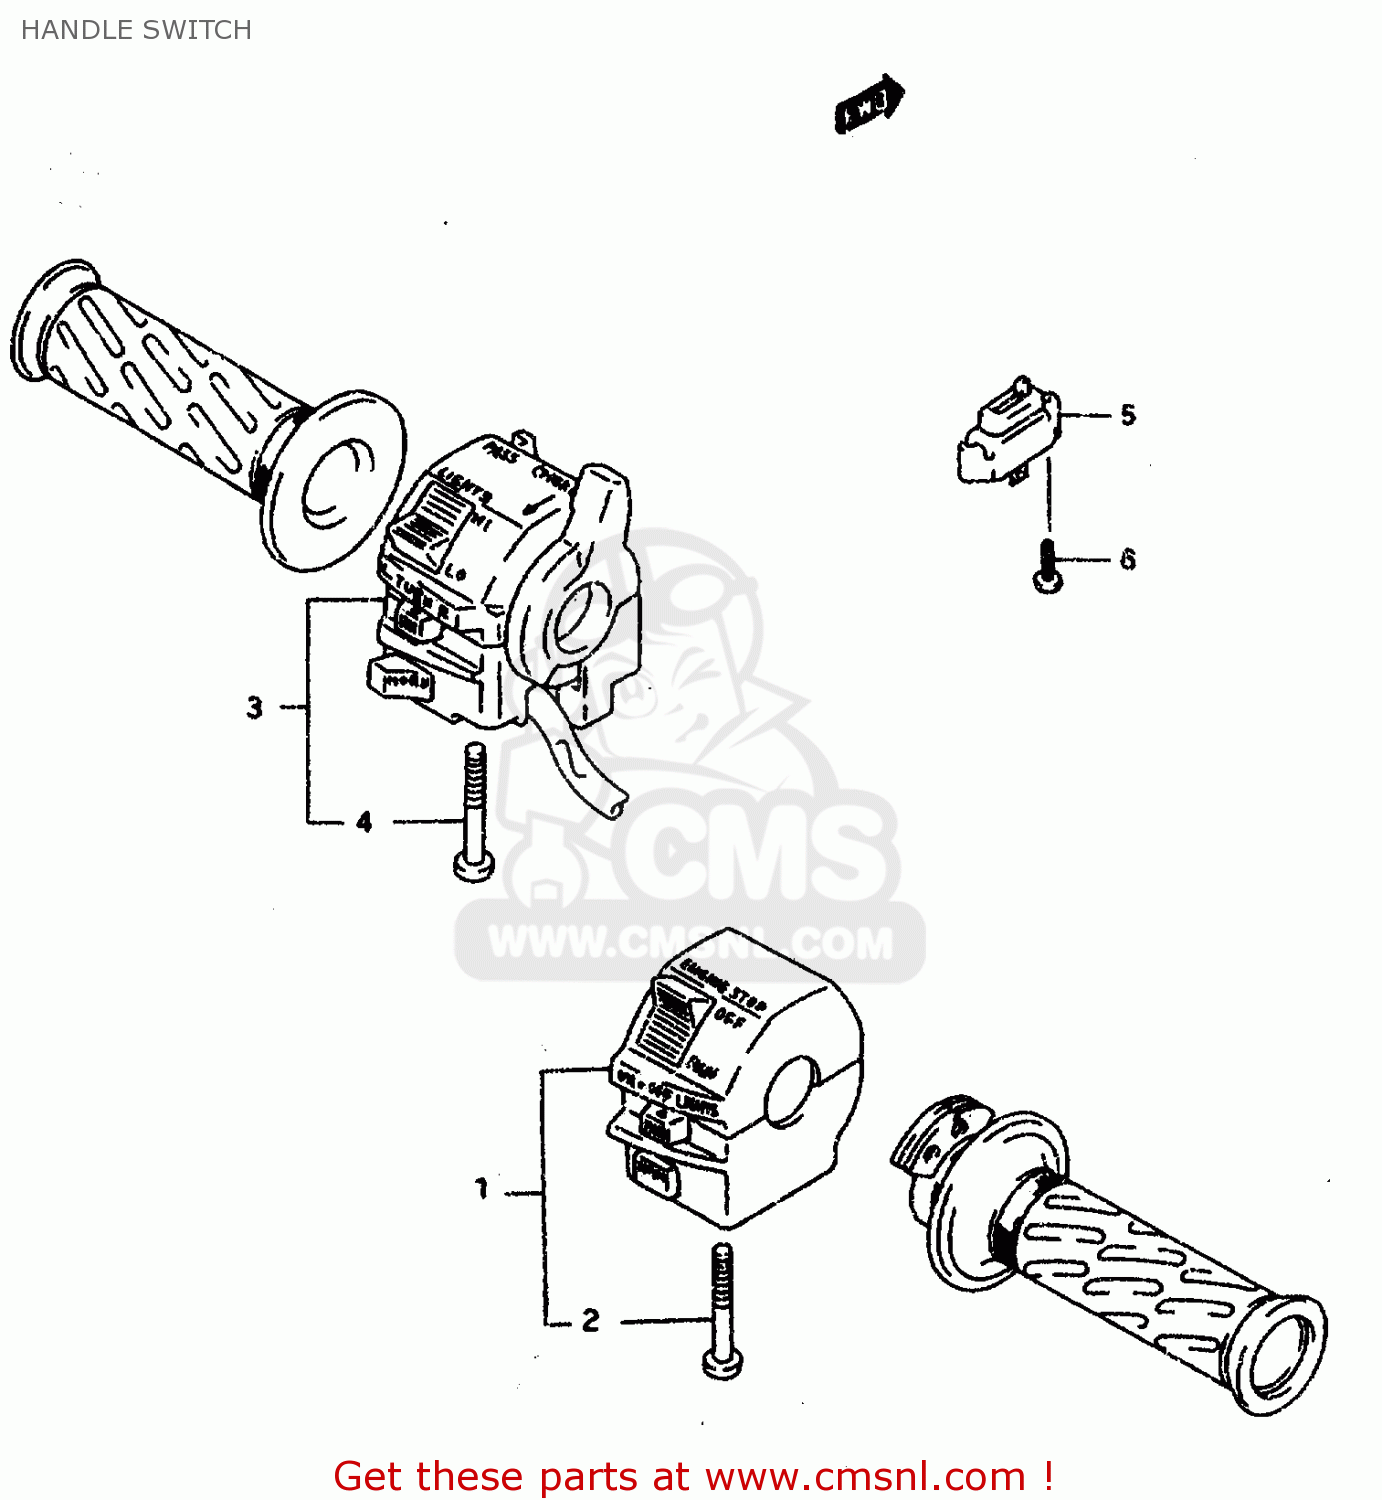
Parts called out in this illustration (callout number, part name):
1	SWITCH,HANDLE,
2	SCREW, 5X45
3	SWITCH,HANDLE,
4	SCREW, 5X45
5	SWITCH ASSY, CLUTCH
6	SCREW
